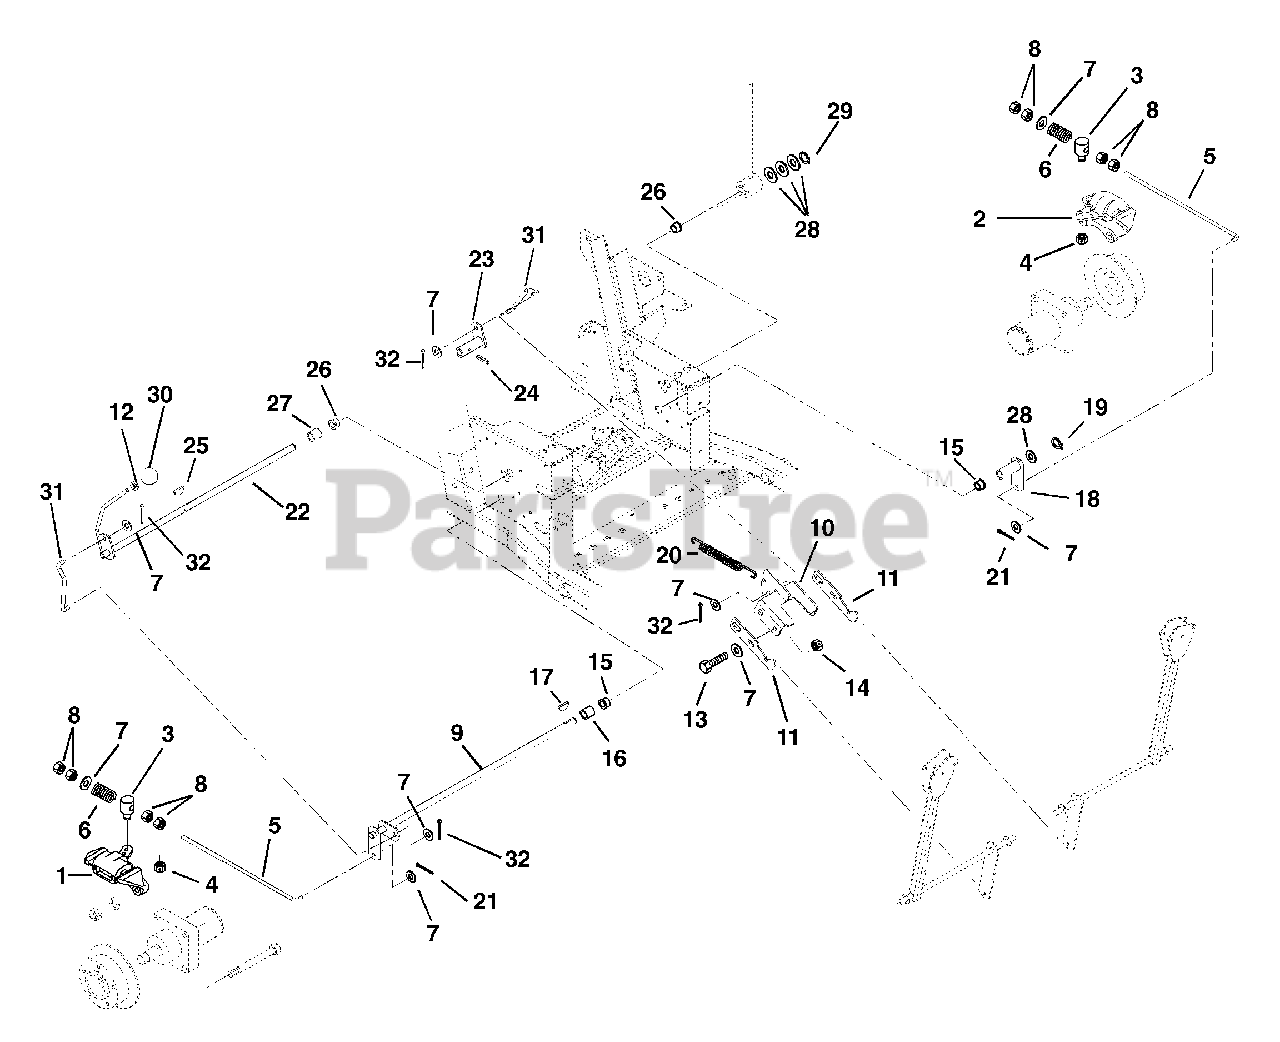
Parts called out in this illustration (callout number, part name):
1	Caliper, Park Brake (CW) Right Hand
2	Caliper, Park Brake (CCW) Left Hand
3	Pivot-Brake Rod
4	Nut-Locking-Center .31 - 18
5	Rod-Brake 12 inch
6	Spring-Compression .143 x .710 x 2.00
7	Washer-Flat-Steel .406 x .812 x .065
8	Nut-Hex .38 - 16
9	Shaft-Brake Cross
10	Interlock-Fixed
11	Interlock-Adjustable
12	Nut-Hex-Jam .375 - 16
13	Bolt-Hex .38 - 16 x 1.00 Grade 5
14	Nut-Locking-Center .38 - 16
15	Bushing-Flange .630 x 1.000 x .625
16	Spacer .630 x .878 x 1.000
17	Key-Woodruff .19 x .75 Hard #9
18	Arm-Brake Left-Hand
19	Ring-Retaining-External .625 x .050
20	Spring-Tension .105 x .85 x 5.00
21	Pin-Cotter External .09 x .75
22	Shaft-Brake Actuating
23	Actuator
24	Pin-Roll .125 x 1.00
25	Key-Woodruff .19 x .75 Hard #9
26	Bushing-Flange .630 x 1.000 x .625
27	Spacer .630 x .878 x 1.000
28	Washer-Flat-Steel .627 x .990 x .032
29	Ring-Retaining-External .625 x .050
30	Knob-Steering Lock
31	Rod-Brake Actuating
32	Pin-Cotter-External .09 x .75
